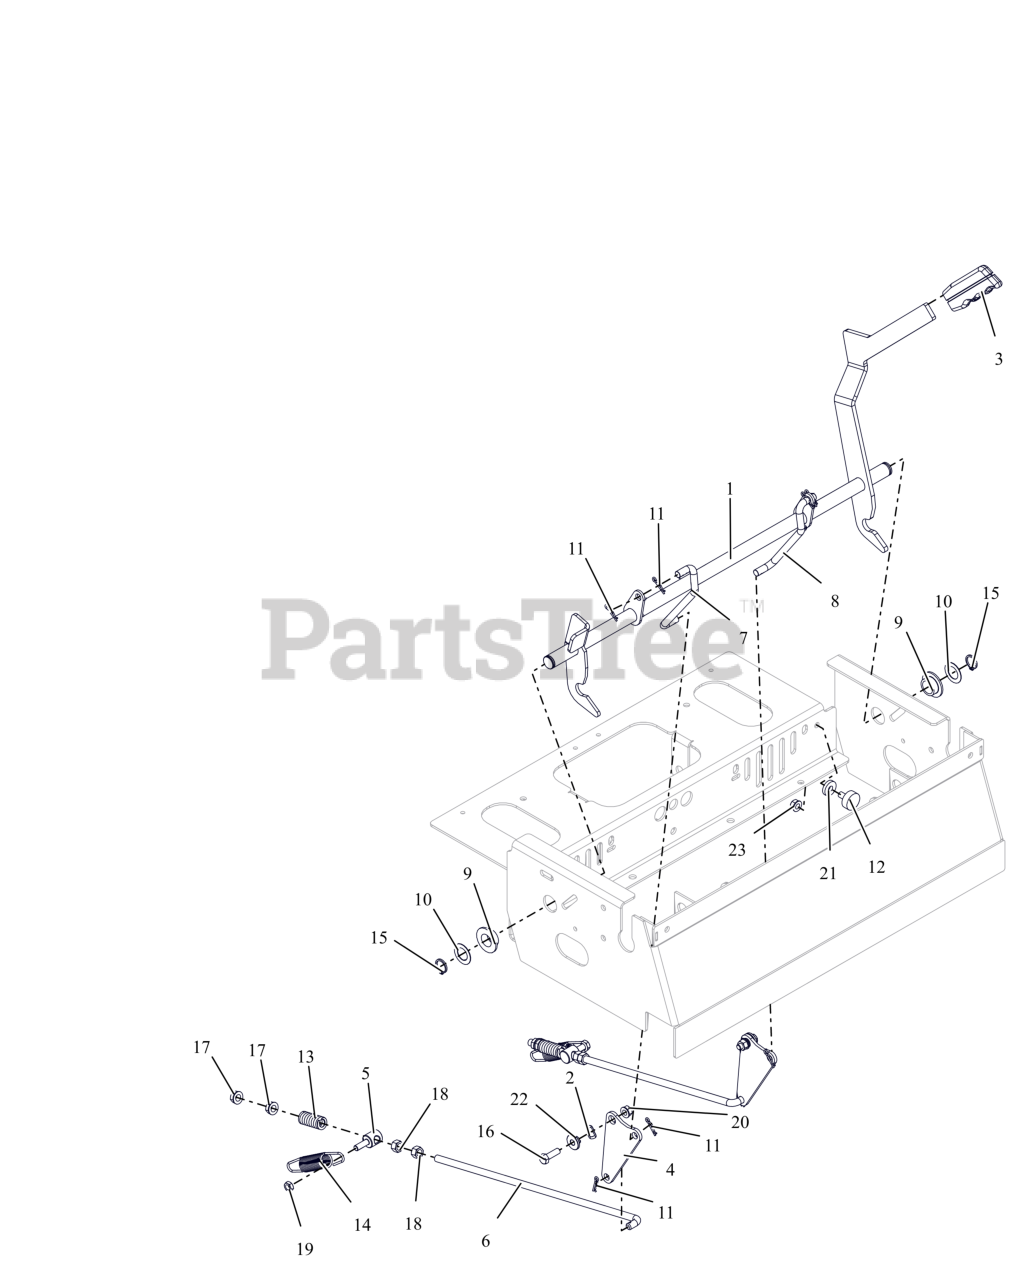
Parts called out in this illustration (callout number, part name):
1	WLDMT, PT200/400 PARK BRAKE
2	WAVE WASHER .531X.781X.125FH
3	GRIP, PARKING BRAKE (YELLOW)
4	PLATE, BRAKE PIVOT
5	TRUNNION, .38-16
6	ROD, BRAKE ADJ.
7	LINKAGE, RH BRAKE ACTUATING
8	LINKAGE, LH BRAKE ACTUATING
9	BSHG-FLG .762X1.48X.44 NYL
10	WSHR-HDND-THRST .758X1.23X.031
11	PIN, HAIR #225 .072X1.09
12	BUMPER, RUBBER
13	SG-COMP .142 X .710 X 1.75
14	SPRING-TENS .105X.850X.4.880
15	RG-RTNG-EXT .689X.078
16	BLT,HEX .31-18X1.00 G5 ZCC
17	NUT, SPNLK-FLG .38-16 G5 ZCC
18	NUT-STD .375-16 G2 ZCC
19	NUT-LK-CTR-JAM .312-18 GB ZCC
20	NUT-LK-TOP-FLG .312-18 GF ZCC
21	WSHR, FLT .328X.870X.179 ZCC
22	BSHG-FLG .32X.500X.344X.880
23	NUT,SPNLK-FLG .31-18 G5 ZCC
